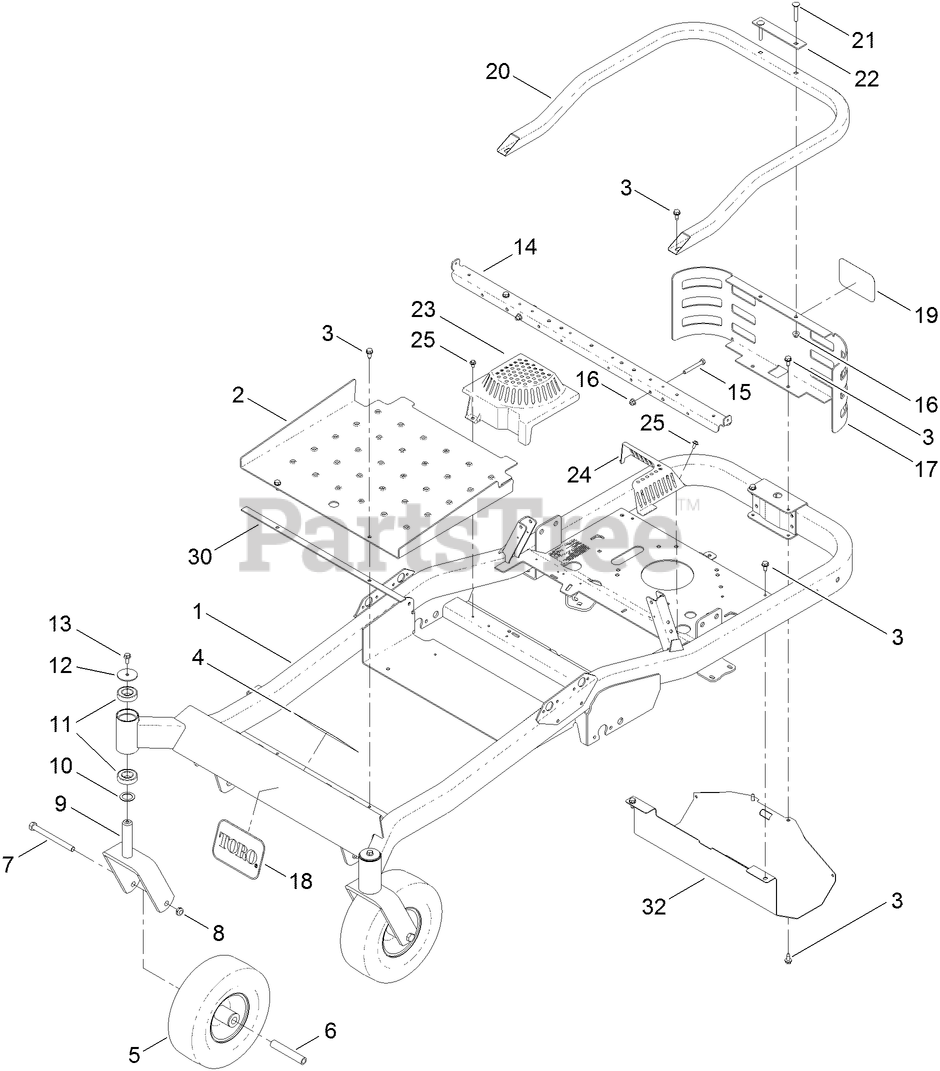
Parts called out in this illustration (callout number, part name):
2	PAN-FLOOR
3	SCREW-HWHTF
4	DECAL-SAFETY
5	TIRE AND WHEEL ASM (KENDA)
6	BUSHING-SPANNER
7	SCREW-HH
8	NUT-HEX
9	CASTER FORK ASM
10	WASHER-THRUST
11	BEARING-BALL
12	WASHER
13	SCREW-HHF
14	SUPPORT-SEAT
15	SCREW-HH
16	NUT-HF, NI
17	GUARD-REAR
18	DECAL
20	GUARD-REAR, TUBE
21	BOLT-CARR
22	PLATE-SPACER
23	COVER-FAN, RH
24	COVER-FAN, LH
25	SCREW-HHFTF
30	STRIP-VIBRATION, ANTI
